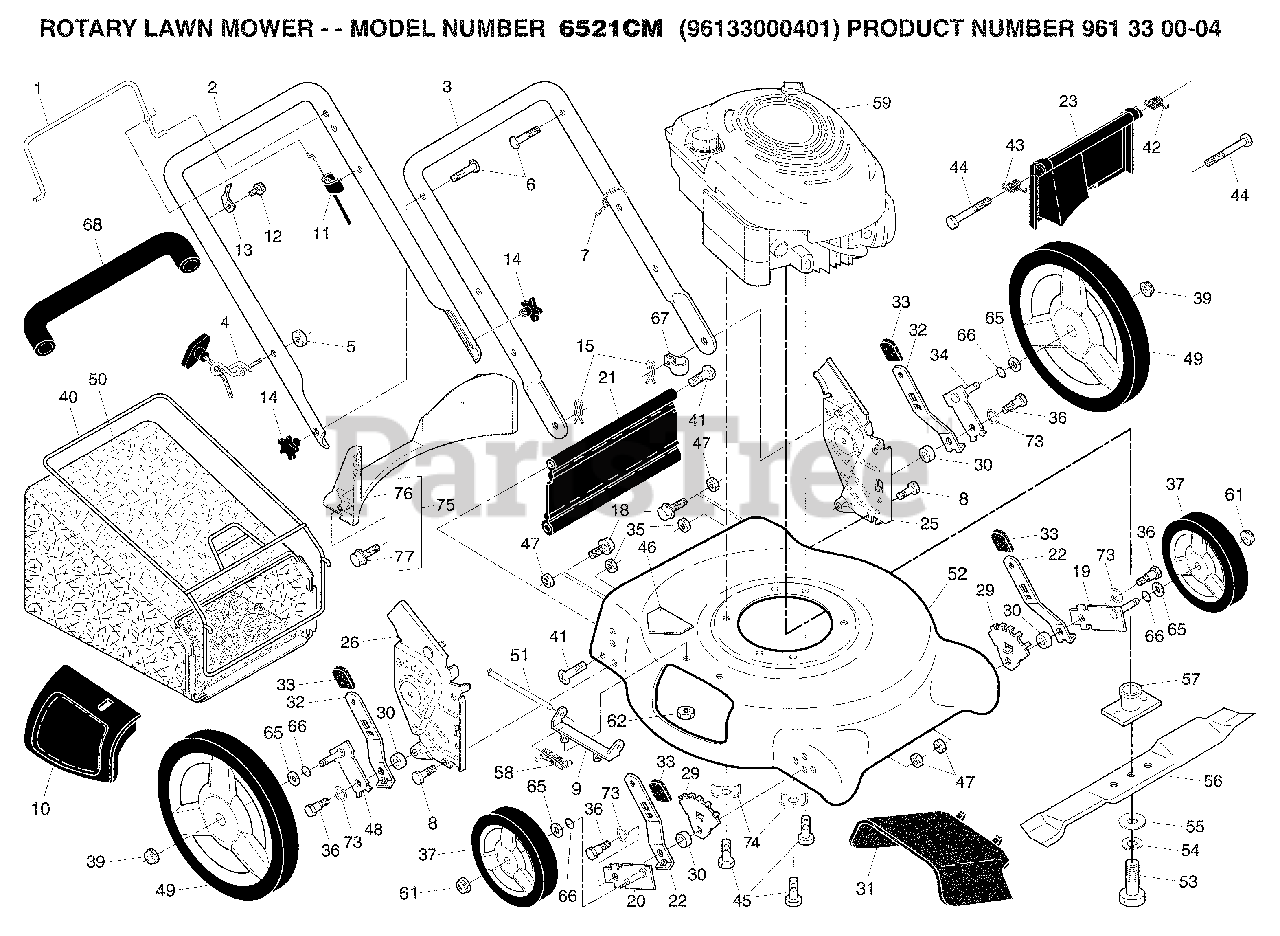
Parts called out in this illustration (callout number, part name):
1	Control Bar
2	Upper Handle
3	Lower Handle
4	Rope Guide
5	Locknut, Hex 1/4-20
6	Handle Bolt
7	Wire Tie
8	Hex Bolt 5/16-18 x 3/4
9	Hinge Bracket Assembly
10	Mulcher Door
11	Engine Zone Control Cable
12	Hex Washer Head Screw #10-24 x 1/2
13	Up-Stop Bracket
14	Handle Knob
15	Hairpin Cotter
18	Screw 1/4-20 x 3/8
19	Axle Arm Assembly, Front, LH
20	Axle Arm Assembly, Front, RH
21	Kit, Rear Skirt
22	Selector Spring, Front
23	Rear Door Assembly
25	Handle Bracket Assembly, LH
26	Handle Bracket Assembly, RH
29	Wheel Adjusting Bracket, Front
31	Discharge Defl ector
32	Selector Spring, Rear
33	Selector Knob
34	Axle Arm Assembly, Rear, LH
35	Nut, Hex
36	Shoulder Bolt 5/16-18
37	Wheel & Tire Assembly, Front 8 x 1-3/4
39	Nut, Hex, Flangelock
40	Frame, Grassbag
41	Hinge Screw
42	Spring, Rear Door, LH
43	Spring, Rear Door, RH
44	Bolt, Rear Door
45	Hex Head Thread Rolling Screw 3/8-16 x 1
46	Danger Decal
47	Locknut, Hex 5/16-18
48	Axle Arm Assembly, Rear, RH
49	Wheel & Tire Assembly, Rear 12 x 1-3/4
52	Kit, Lawn Mower Housing Assembly
53	Hex Head Screw 3/8-24 x 1-3/8 Grade
54	Helical Lockwasher
55	Hardened Washer
56	21" Blade
57	Blade Adapter
58	Spring, Torsion
61	Nut, Hex, Flangelock
62	Nut, Hex, Nylock 1/4-20
65	Washer, Flat
67	Clip, Cable
68	Grip, Foam
73	Washer, Flat
74	Washer, Special, Engine, Zinc-Plated
75	Kit, Rear Baffle
76	Baffl e, Rear
77	Screw, Rear Baffl e
